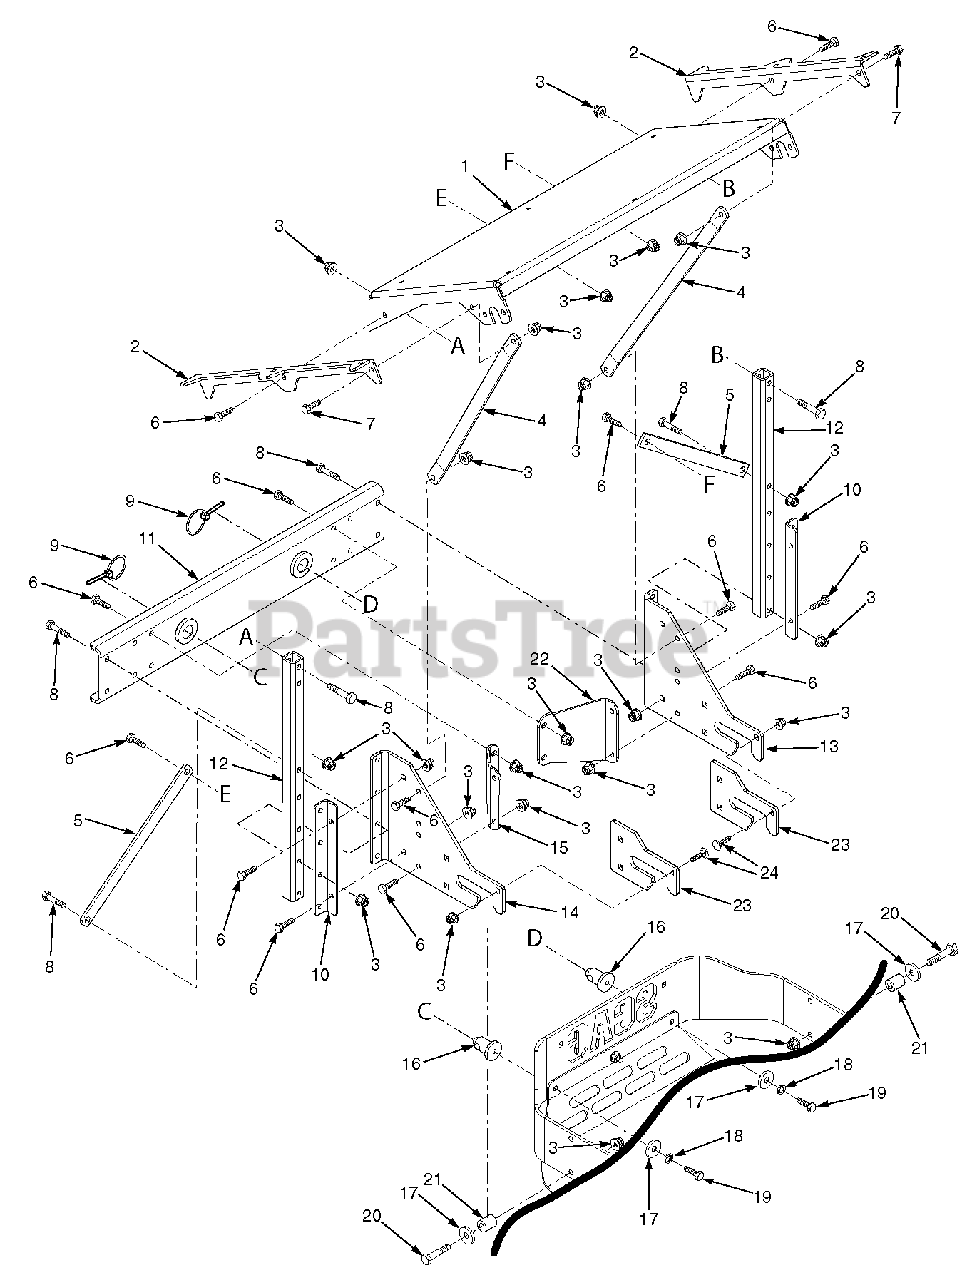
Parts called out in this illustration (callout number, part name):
1	Support Frame, Hopper
2	Bracket, Hopper Support
3	Nut, Elastic Flange 3/8-16
4	Brace, Stiffener
5	Brace, Engine Mount
6	Bolt, Hex Head 3/8-16 x 1"
7	Bolt, Hex Head 3/8-16 x 1-1/4"
8	Bolt, Hex Head 3/8-16 x 2-1/4"
9	Quick Pin
10	Mounting Bracket, Tube
11	Mounting Bracket Weldment
12	Tube, Upright
13	Mounting Bracket, GC R.H.
14	Mounting Bracket, GC L.H.
15	Angle Bracket, GC
16	Pin, GC Locator
17	Flatwasher, 3/8-.406 x 1.50 x 7 Ga.
18	Lockwasher, 3/8"
19	Bolt, Hex Head 3/8-16 x 1-1/4"
20	Bolt, Hex Head 3/8-16 x 2-1/4"
21	Spacer
22	Angle Bracket, GC
23	Wear Plate, GC
24	Bolt, Carriage 3/8-16 x 1-1/4"
